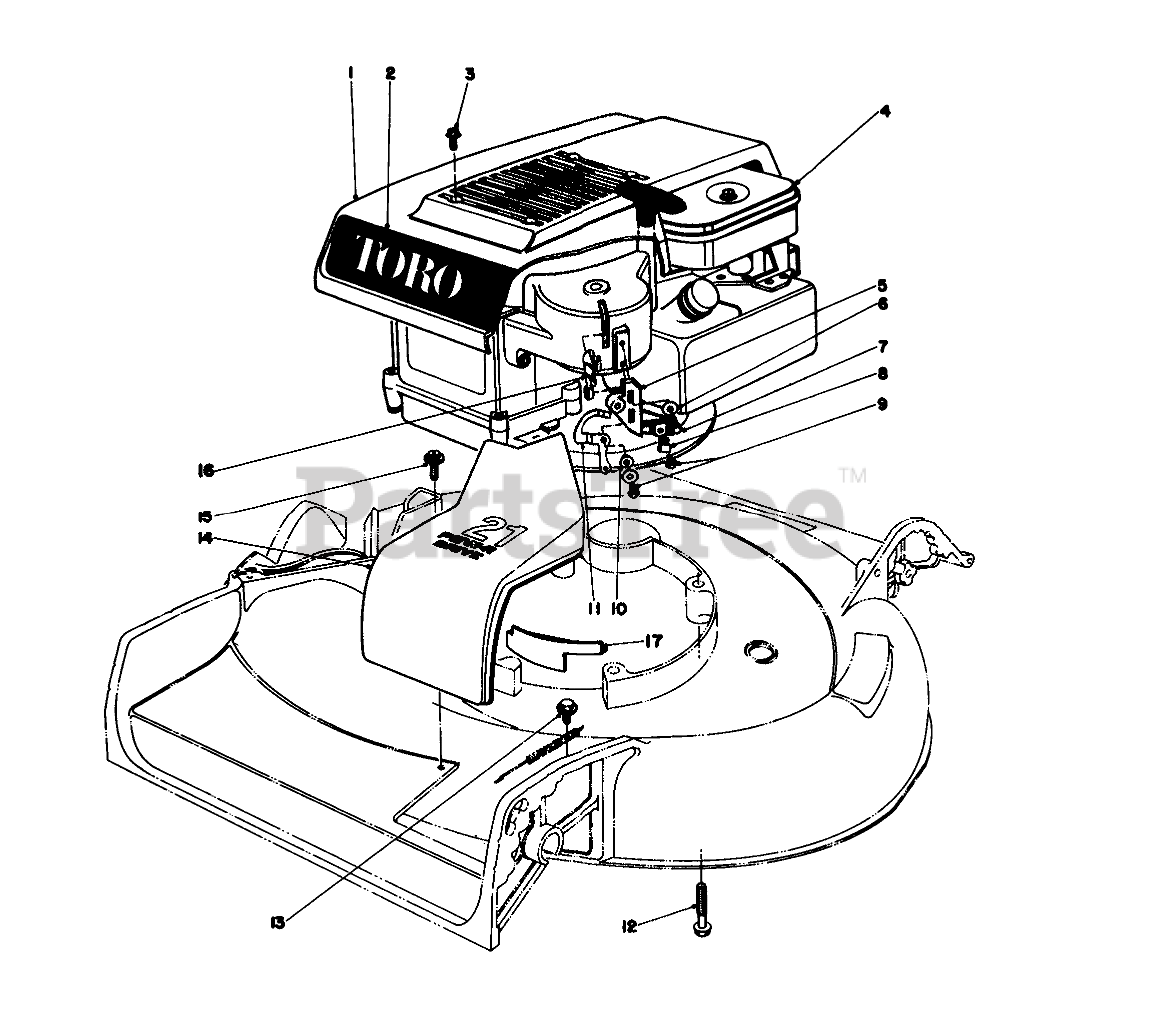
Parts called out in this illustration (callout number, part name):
1	SHROUD
2	Decal-Toro
3	Screw
4	Engine
5	CABLE & PIVOT BLOCK
6	WASHER-FLAT
7	Screw
8	CLAMP
9	Screw
10	BUSHING
11	CAM INTERLOCK
12	3/8-16 X 2-3/4 CAPSCR
13	Screw-Self Tapping
14	BELT DRIVE COVER
15	SCREW
16	INTERLOCK LEVER
17	HOUSING CAP
